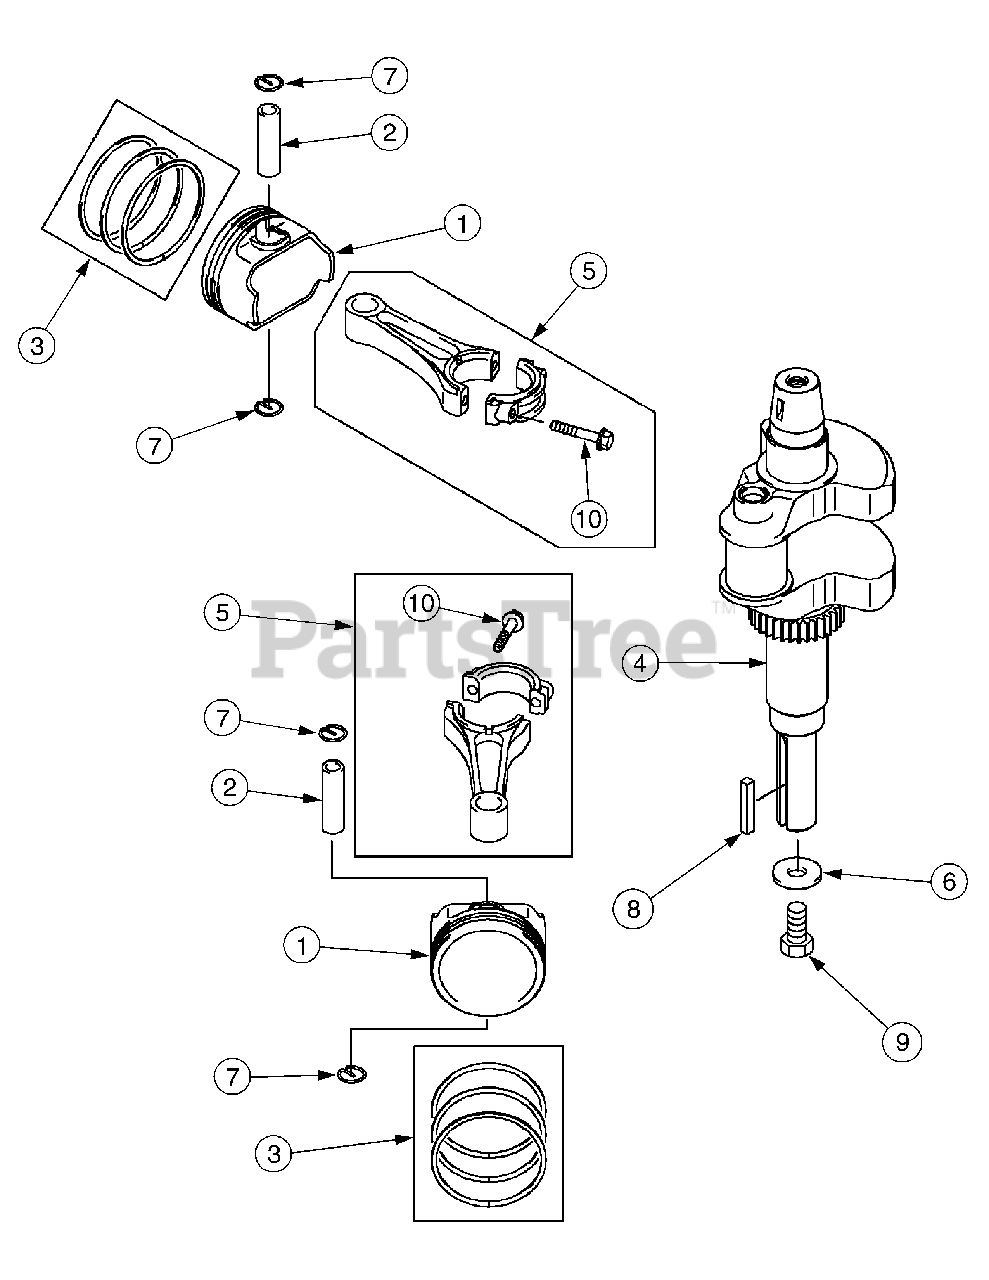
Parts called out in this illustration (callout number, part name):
1	Piston, Engine
1	Piston, Engine, L 0.50
3	Ring Set, Piston
3	Ring Set, Piston, L 0.50
5	Rod, Connecting
6	Washer, 12.5 x 32 x 3.2
7	Lock Ring, Piston Pin
8	Key, Flywheel
9	Bolt, 7/16-20UNF
10	Bolt, 6 x 35
